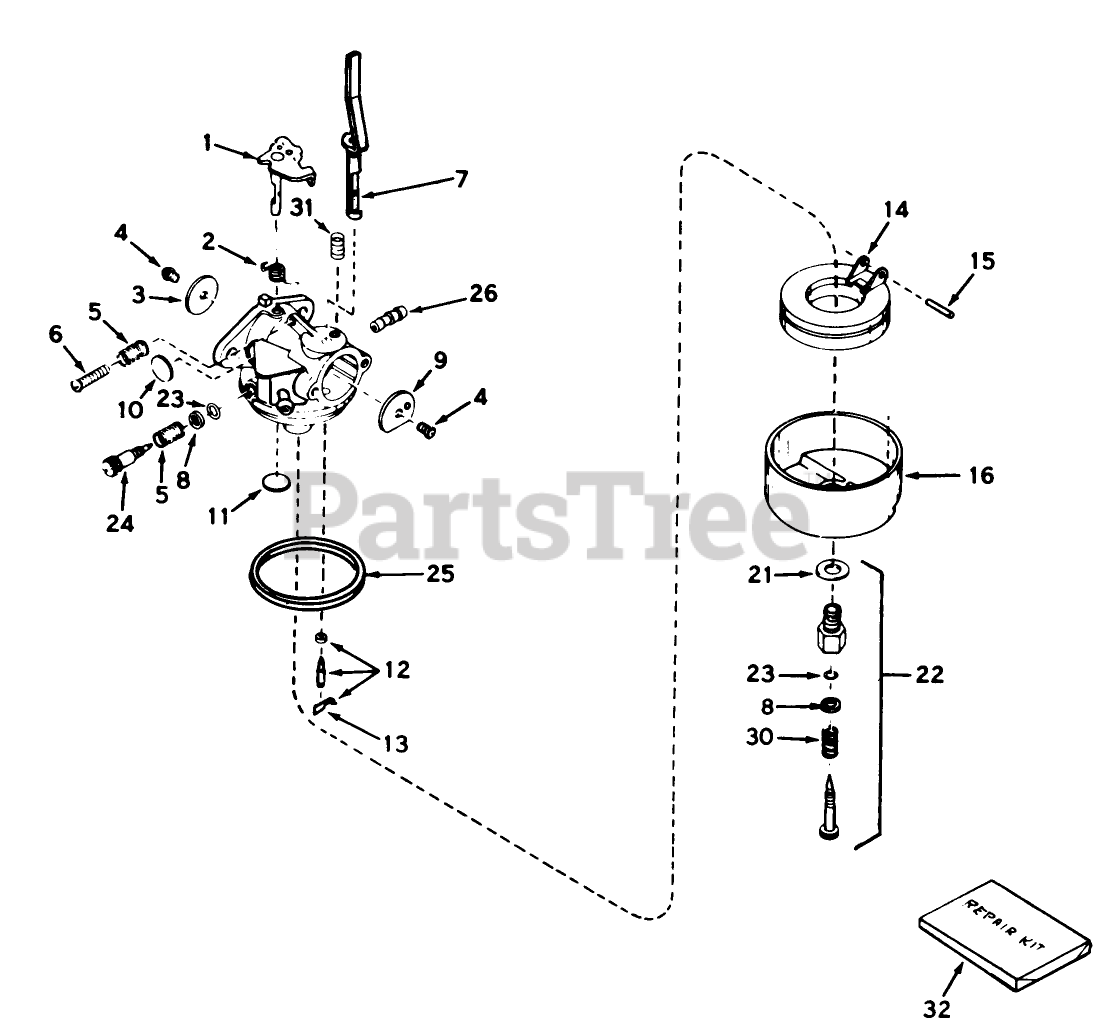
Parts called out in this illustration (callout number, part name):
1	Shaft/Lever-Throttle
2	Spring, Return
3	Shutter-Throttle
4	Screw-Shutter
5	Spring-Tension
6	Screw-Throttle Crack Screw / Idle Speed
7	Shaft Lever Assy., Choke
8	Washer
9	Shutter-choke
10	Plug-Welch, Idle Mixture Well
11	Plug-Welch, Atmospheric Vent
12	Inlet Needle, Seat Clip Assy. (Incl. No. 13)
13	Clip-Spring
14	Float,Carburetor
15	Shaft-Float
16	Bowl-Float (no drain)
21	Washer-Bowl Nut
22	Adjustment Screw Assy., Main (Incl. Nos. 5A, 21 23)
23	ORing
24	Screw, Idle Adj.
25	O Ring-Bowl, Float
26	Fuel Fitting
30	Spring
31	Spring-Positioning, Choke
32	Repair Kit (Incl. items marked *)
